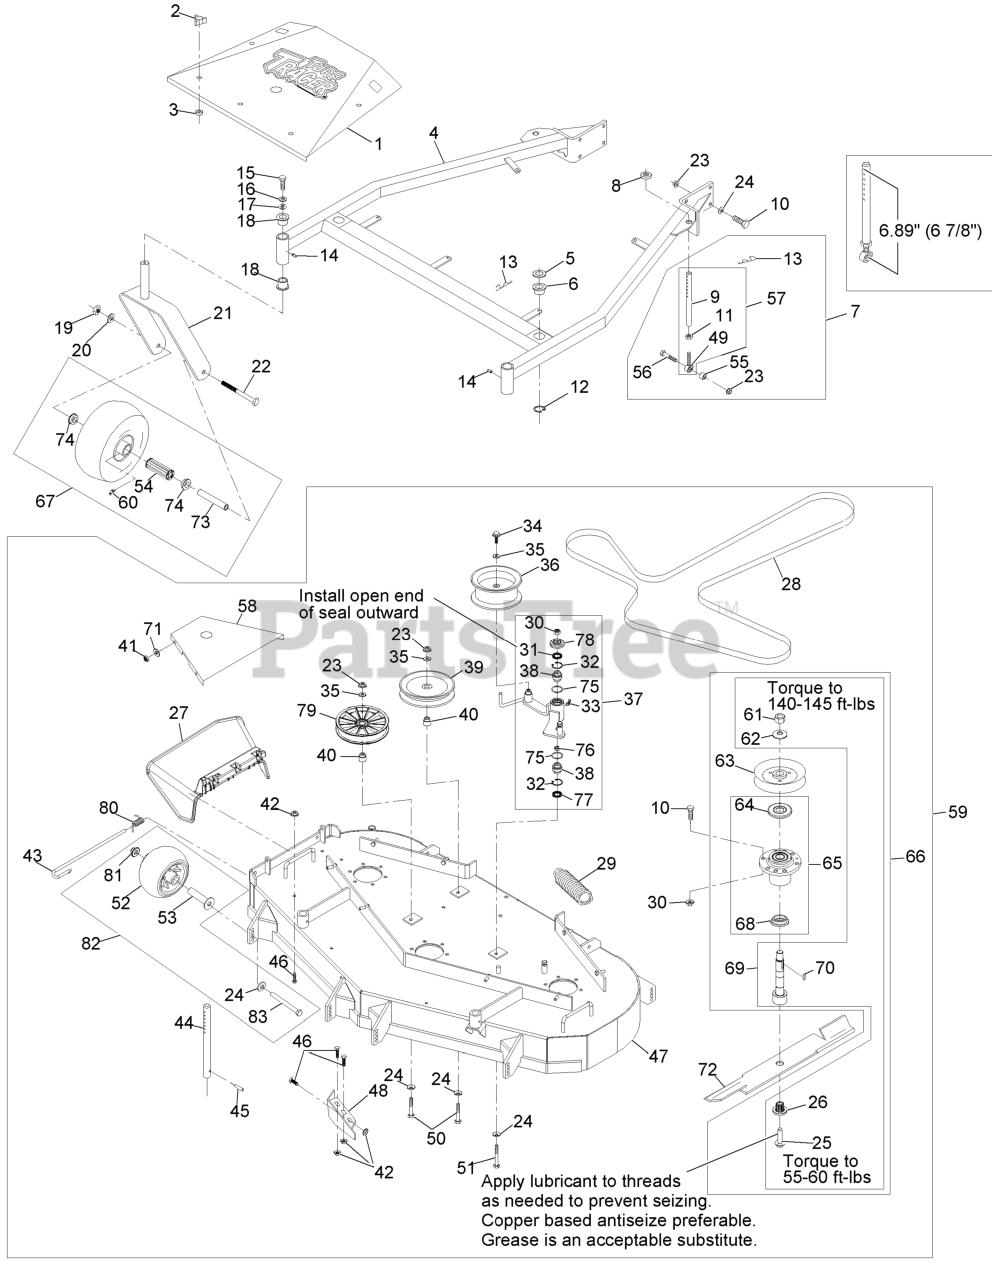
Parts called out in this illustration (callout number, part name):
1	ASM,SHIELD W/DECALS 52 TT
2	KNOB-3 PRONG
4	SUPPORT,DECK W/BUSHINGS
5	SPACER-DECK SUPPORT
6	BUSHING-DECK
7	KIT,SUPPORT LINK W/PIN
9	LINK,SUPPORT
10	SCREW-HH
11	NUT-HJ
12	RING-RETAINING
13	PIN,HAIR COTTER
14	FITTING-GREASE
15	SCREW-HH
16	WASHER-LOCK
18	BEARING-FLANGED
19	NUT-HH
20	WASHER-LOCK
22	SCREW-HH
23	NUT-HHF, WHIZ
24	WASHER-BELLEVILLE
25	SCREW,SEMS 1/2-20 X 2.19
26	BUSHING,SPLINED
27	CHUTE DEFLECTOR XRK M056
28	BELT,DECK DRIVE
30	NUT-LOCK, NI
31	SEAL-LIP, SINGLE
32	RING-SNAP
33	FITTING-GREASE, 90 DEG
34	SCREW-HHF
35	WASHER-FLAT
36	IDLER-PULLEY, FLAT
37	KIT, DECK IDLER TTHP48&52
38	BEARING-SPHERICAL
39	PULLEY-IDLER
40	BUSHING-IDLER
41	NUT-LOCK, NI
43	PIN-CHUTE
44	ROD,DECK SUPPORT
46	SCREW-HH
47	ASM,DECK W/DECALS TTHP52
48	Baffle, Discharge
49	BALLJOINT
50	SCREW-HH
51	SCREW-HH
52	ROLLER-SCALP, ANTI
53	AXLE, ROLLER
54	BEARING
56	SCREW-HH
58	SHIELD,SIDE BELT 52
59	Asm, Deck Complete
60	FITTING-GREASE
63	SHEAVE,W/HUB 5.72
64	GUARD-BEARING, TOP
65	KIT, CUTTER HOUSING
66	ASM, CUTTER HSG
67	KIT, SP CASTER WHEEL REPL
68	SPACER-GUARD, BOTTOM
69	KIT, SPLINED SPINDLE 103-
70	KEY-RECTANGLE
71	WASHER-FLAT
74	BUSHING
77	SEAL-LIP, DOUBLE
78	GUARD-TOP
79	PULLEY,IDLER 5"
80	SPRING, TORSION
81	Nut-Nyloc 3/8-16 Flg
82	KIT, ANTI-SCALP ROLLER
83	SCREW-HH 3/8-16 X 3 3/4 GR 8
